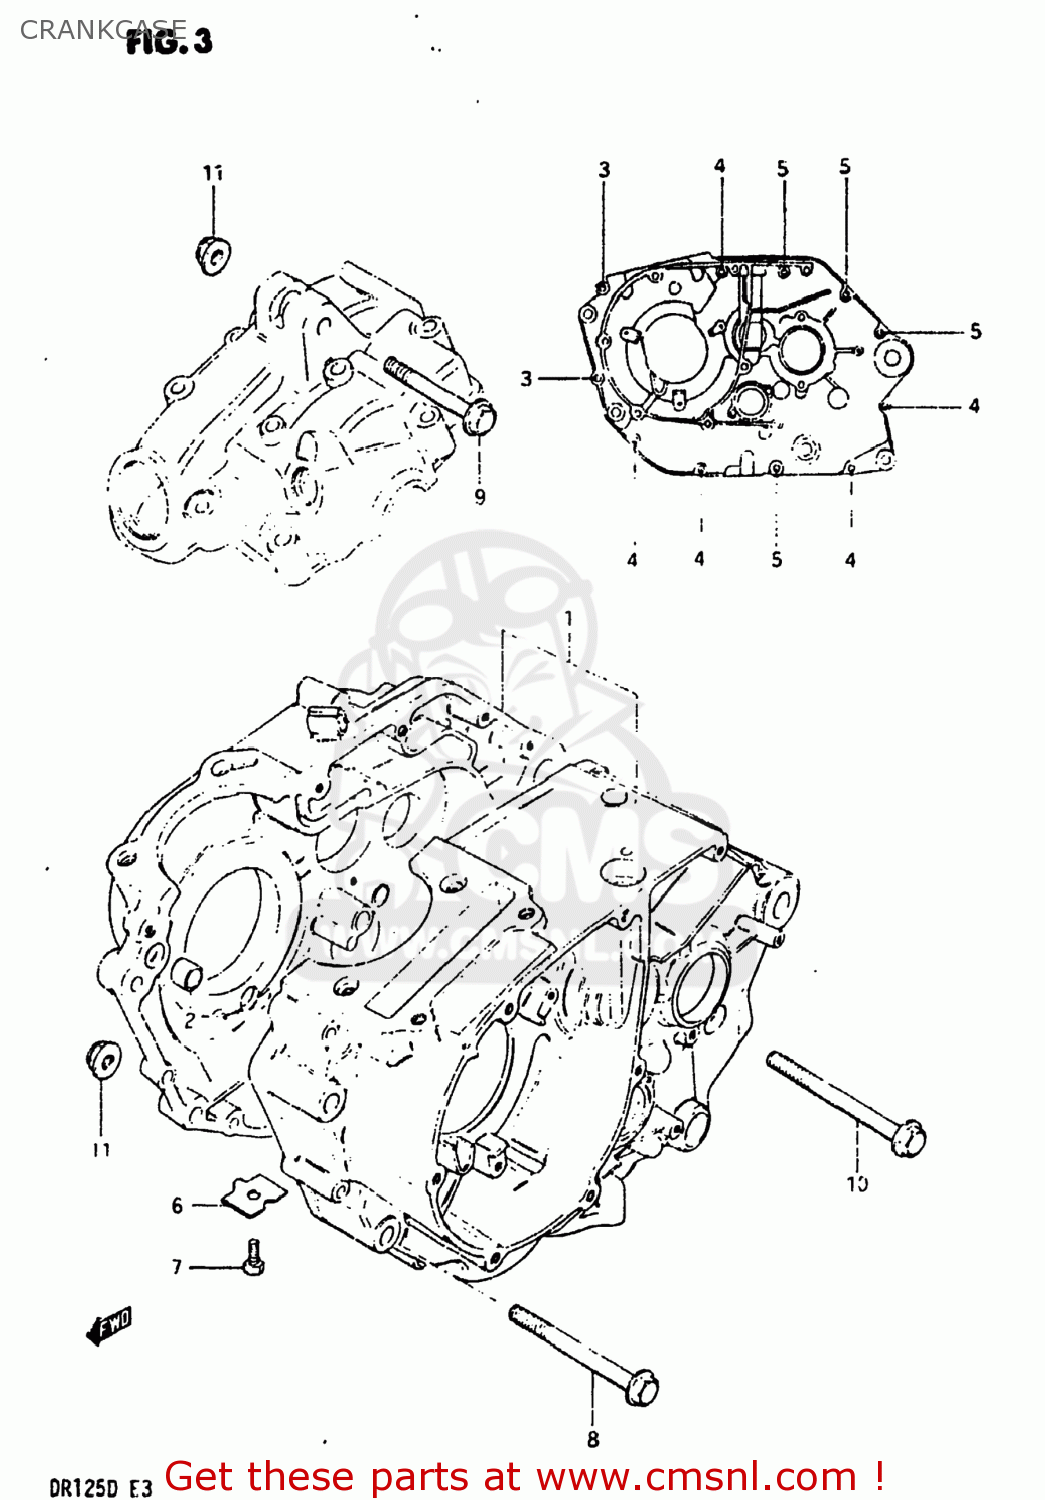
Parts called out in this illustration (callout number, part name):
1	CRANKCASE SET
2	PIN
3	BOLT (6X45)
4	BOLT (6X60)
5	BOLT (6X75)
6	PLATE,OIL GALLERY PLUG
7	BOLT
8	BOLT(8X80)
9	BOLT 8X50
10	BOLT 8X88
11	NUT
